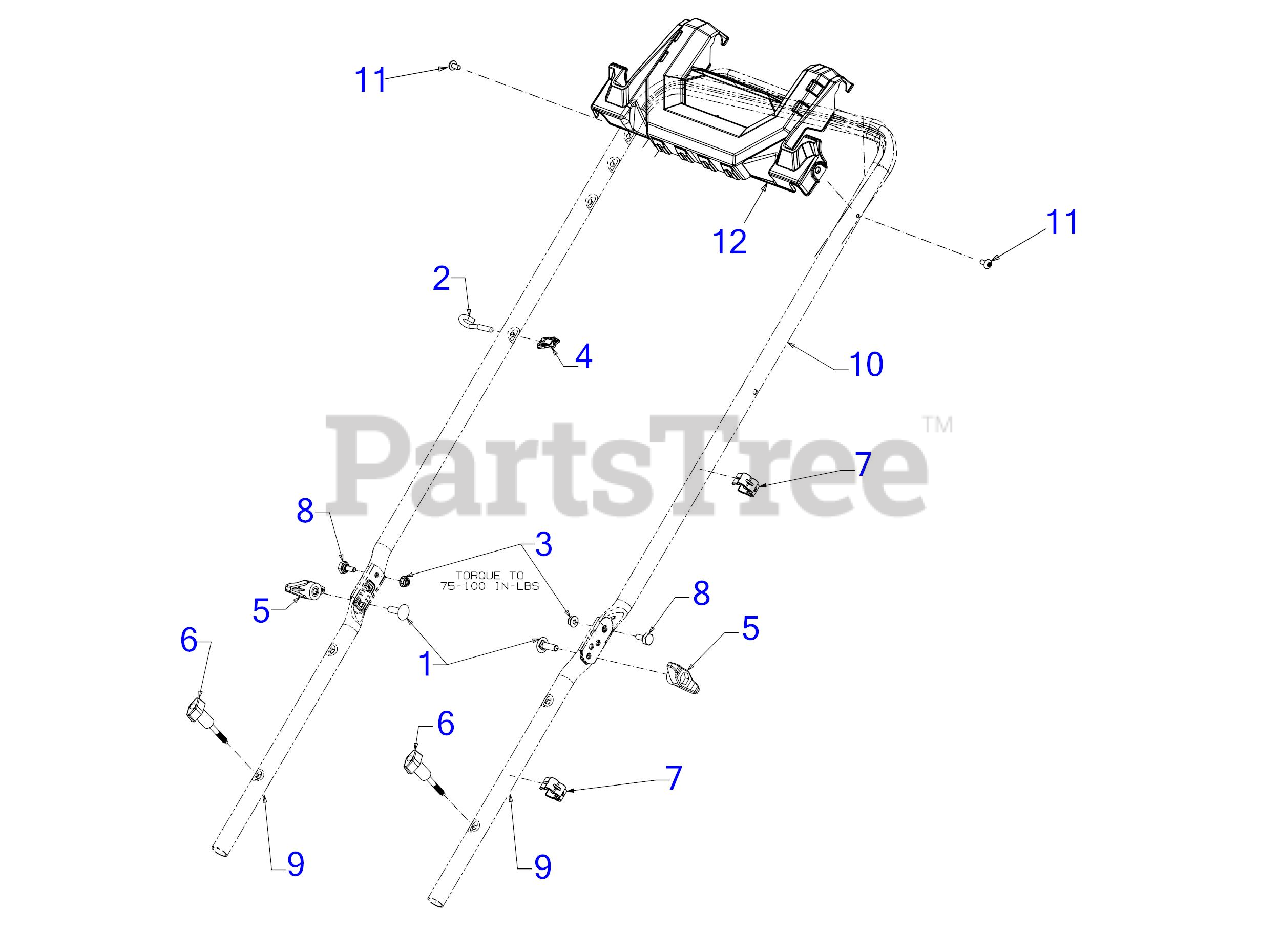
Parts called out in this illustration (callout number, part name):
1	SCREW 5/16-18 x 1.00 GR5
2	EYEBOLT 1/4-20
3	FLANGE LOCK NUT
4	HANDLE KNOB
5	WING KNOB 5/16-18
6	WING KNOB 1/4-20
7	CONDUIT CLIP
8	SHOULDER SCREW
9	LOWER HANDLE
10	UPPER HANDLE
11	SCREW 1/4-14 x .625
12	HANDLE CONSOLE
